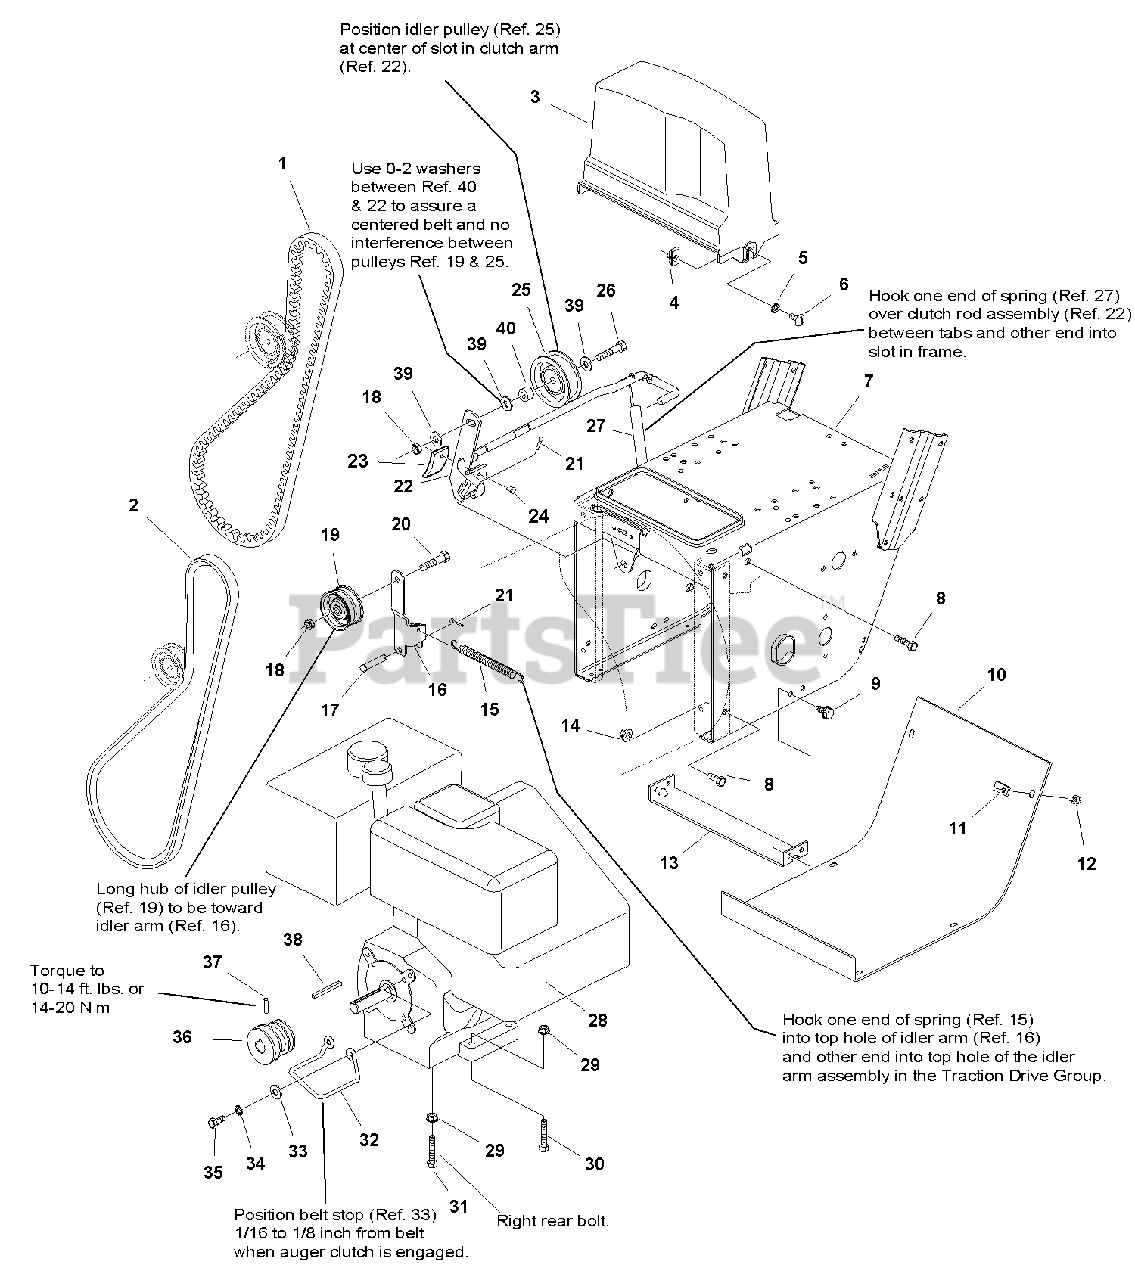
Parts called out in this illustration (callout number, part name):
1	BELT, Traction
2	BELT, Drive Auger
3	GUARD, Belt
4	NUT, Speed, 5/16-18
5	LOCKWASHER, Ext. Tooth, 5/16
6	SCREW, Truss Head, 5/16-18 x 3/4
7	FRAME, Main
8	CAPSCREW, Whizlock, 5/16-18 x 3/4
9	CAPSCREW, Taptite, 5/16-18 x 3/8
10	COVER, Bottom
11	NUT, Speed, 1/4-20
12	CAPSCREW, Taptite,1/4-20 x 1/2
13	SUPPORT, Tie Bar
14	NUT, Hex, Whizlock, 5/16-18
15	SPRING, Idler
16	ARM, Idler, Traction
17	PIN
18	LOCKNUT, Jam, 3/8-16
19	PULLEY, Idler
20	CAPSCREW, Hex Head, 3/8-16 x 1-1/2
21	PlN, Cotter, 1/8 x 3/4
22	CLUTCH ROD & BRAKE ASSEMBLY
26	CAPSCREW, Hex Head, 3/8-16 x 1-3/4
27	SPRING, Extension
29	NUT, Hex, 5/16-18
30	CAPSCREW, Hex Head, 5/16-18 x 1 3/4
31	CAPSCREW, Hex Head, 5/16-18 x 2
32	GUIDE, Belt
33	WASHER,11/32 x 3/4
34	LOCKWASHER, 5/16
35	CAPSCREW, Hex Head, 5/16-24 x 3/4
36	PULLEY, Traction
37	SETSCREW, .625 LG
38	KEY, Parallel, 3/16 x 13/16 x 7/8
39	WASHER, Flat,13/32
